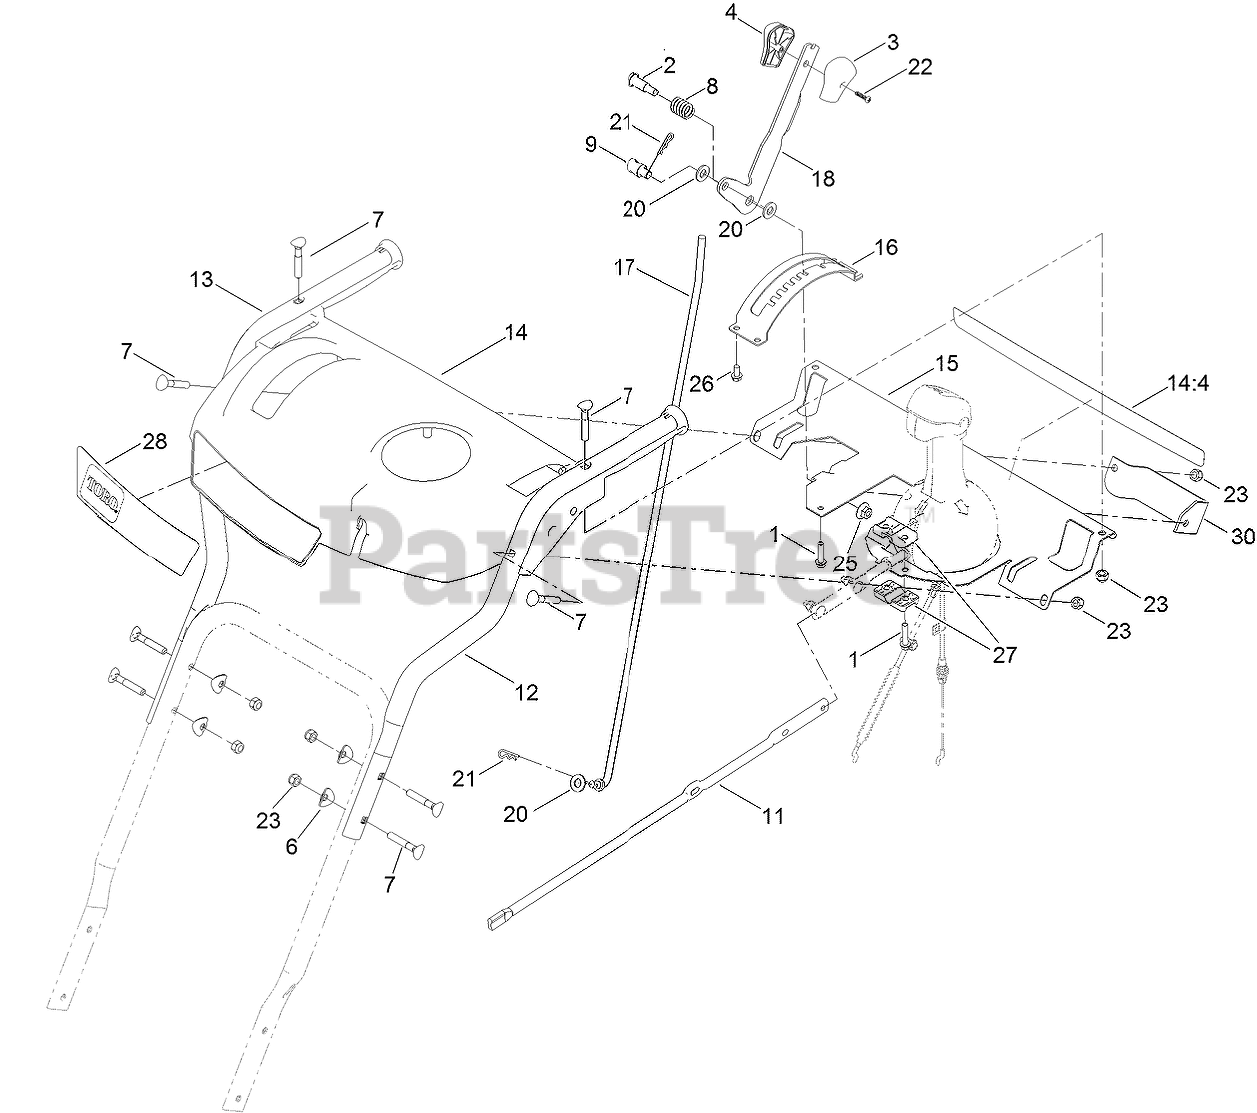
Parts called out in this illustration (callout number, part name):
1	SCREW-PLASTITE, HWH
2	SCREW-SHOULDER, HH
3	KNOB-SHIFT, LH
4	KNOB-SHIFT, RH
6	WASHER-CUP
7	SCREW-HANDLE
8	SPRING-COMPRESSION
9	TRUNNION-ROD
11	ROD-CHUTE
12	HANDLE-UPPER, LH
13	HANDLE-UPPER, RH
14	CONTROL PANEL ASM
14:4	DECAL-SAFETY
15	SUPPORT-PANEL, CONTROL
16	MOUNT-SELECTOR, SPEED
17	ROD-SELECTOR, GEAR
18	SELECTOR-SPEED
20	WASHER-THRUST
21	PIN-HAIR
22	SCREW-PPH
23	NUT-HEX
25	NUT-HF
26	SCREW-PLASTITE
27	SUPPORT-ROD
28	DECAL-MODEL
30	PLATE-SUPPORT, SHIFT
